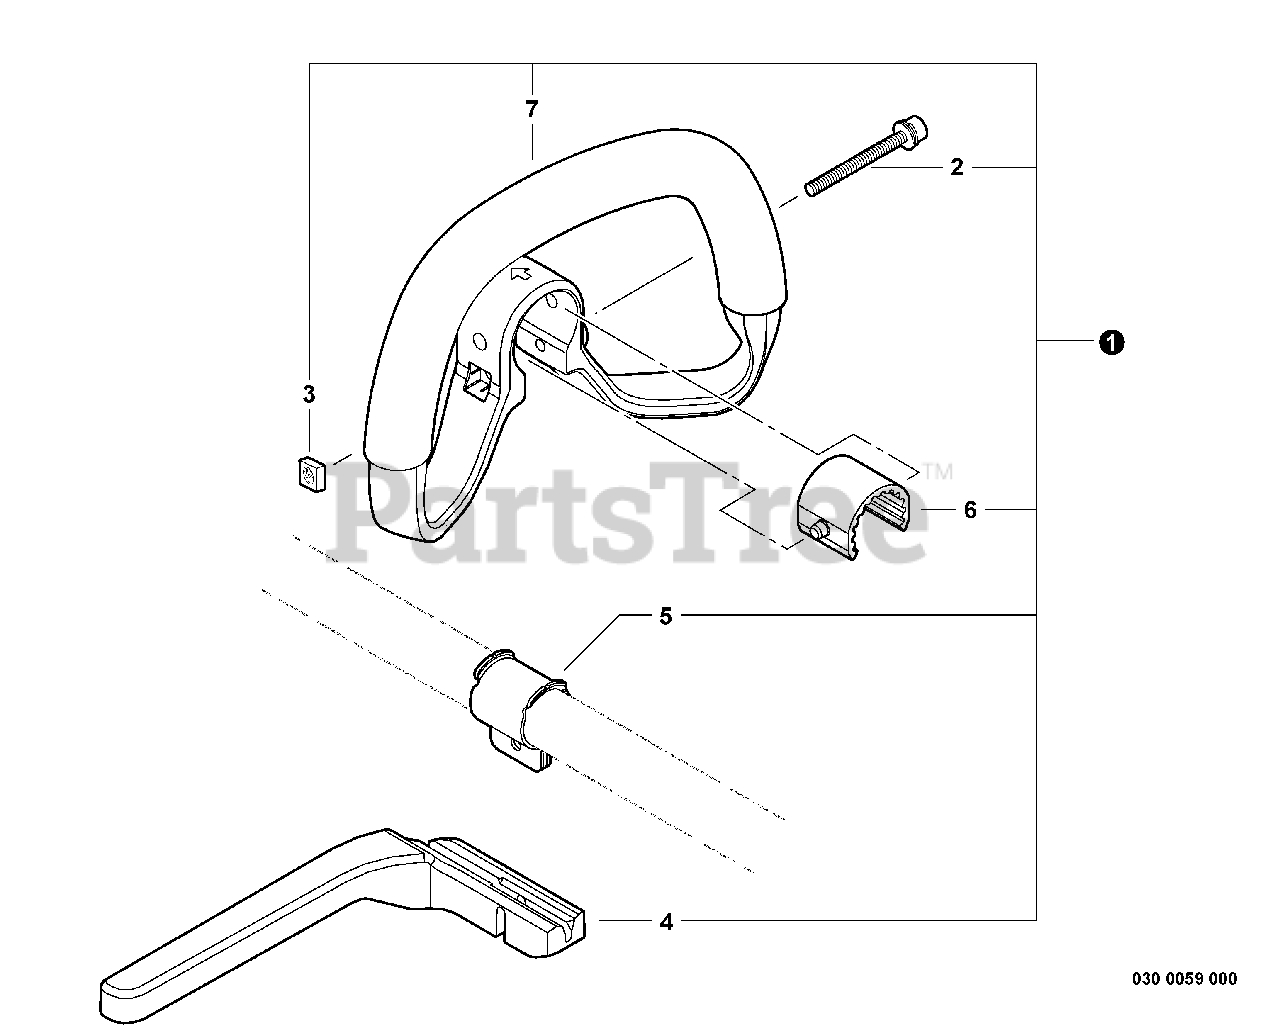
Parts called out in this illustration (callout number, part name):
1	HANDLE ASSY - FRONT
2	SCREW - 5X45
3	NUT - 5
4	BAR, BARRIER
5	BRACKET, HANDLE
6	CUSHION
7	HANDLE - FRONT
